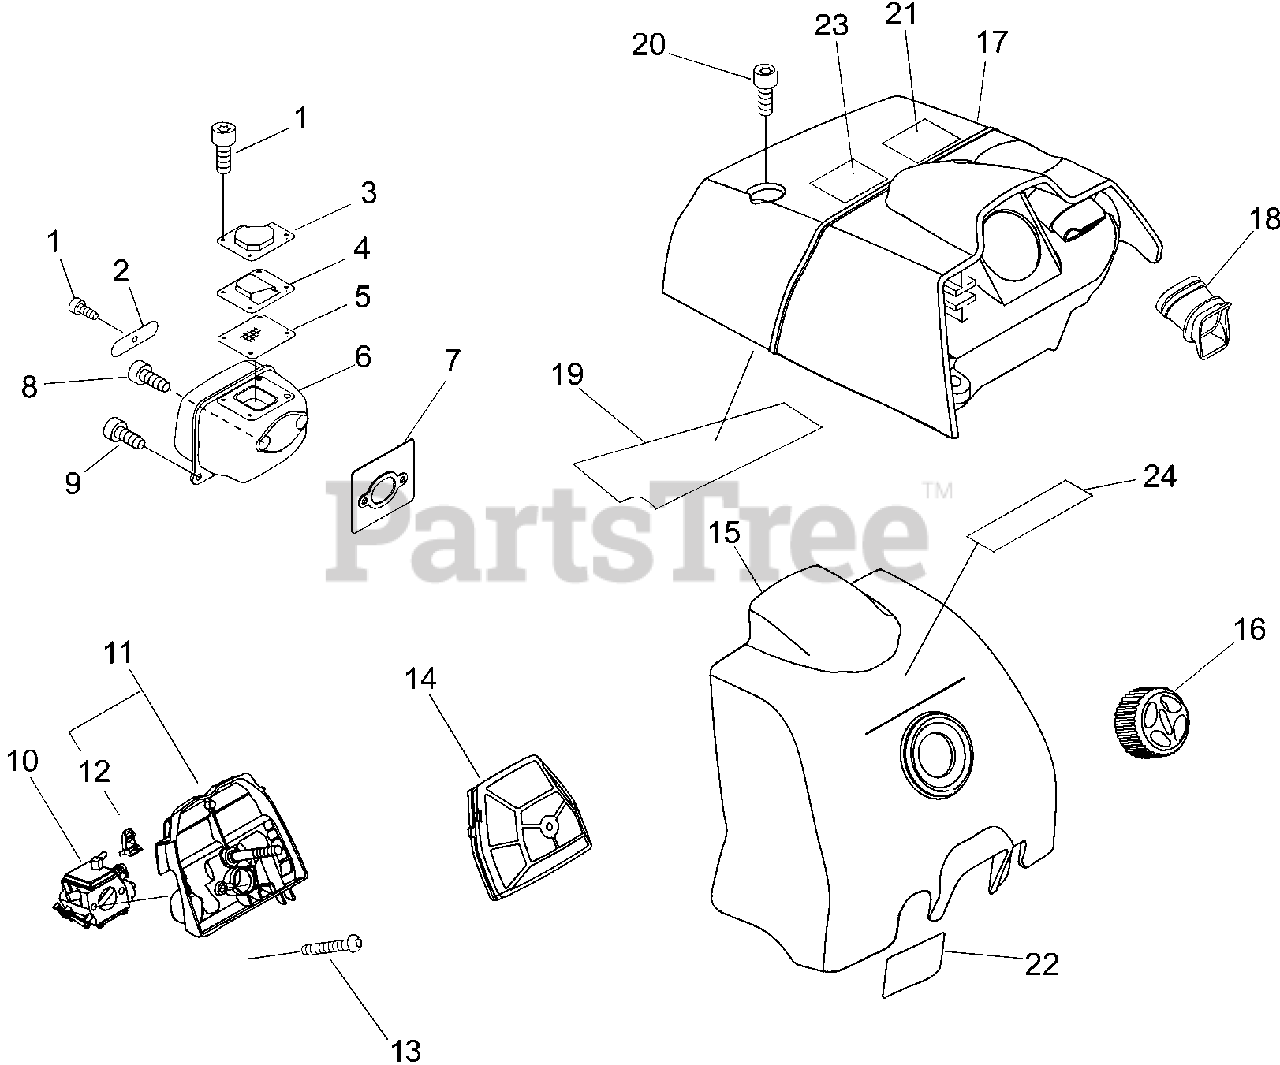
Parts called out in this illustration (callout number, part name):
1	BOLT, TORX 4×8
2	PLATE, MUFFLER
3	GUIDE, EXHAUST
4	GUIDE, EXHAUST
5	SCREEN, SPARK ARRESTER
6	MUFFLER
7	GASKET, EXHAUST
8	BOLT, TORX 5×20
9	BOLT, TORX 5×20
10	CARBURETOR - HDA-274
11	CASE ASSY, AIR FILTER
12	SHUTTER, AIR
13	BOLT, TORX 5×50
14	FILTER ASSY, AIR
15	COVER, AIR FILTER
16	KNOB, AIR FILTER COVER
17	COVER, ENGINE
18	PIPE, INTAKE
19	SHIELD, HEAT 75×32×0.15
20	BOLT, TORX 5×16
21	LABEL, CAUTION
22	LABEL, STOP
23	LABEL, CAUTION
24	LABEL, CS-600
